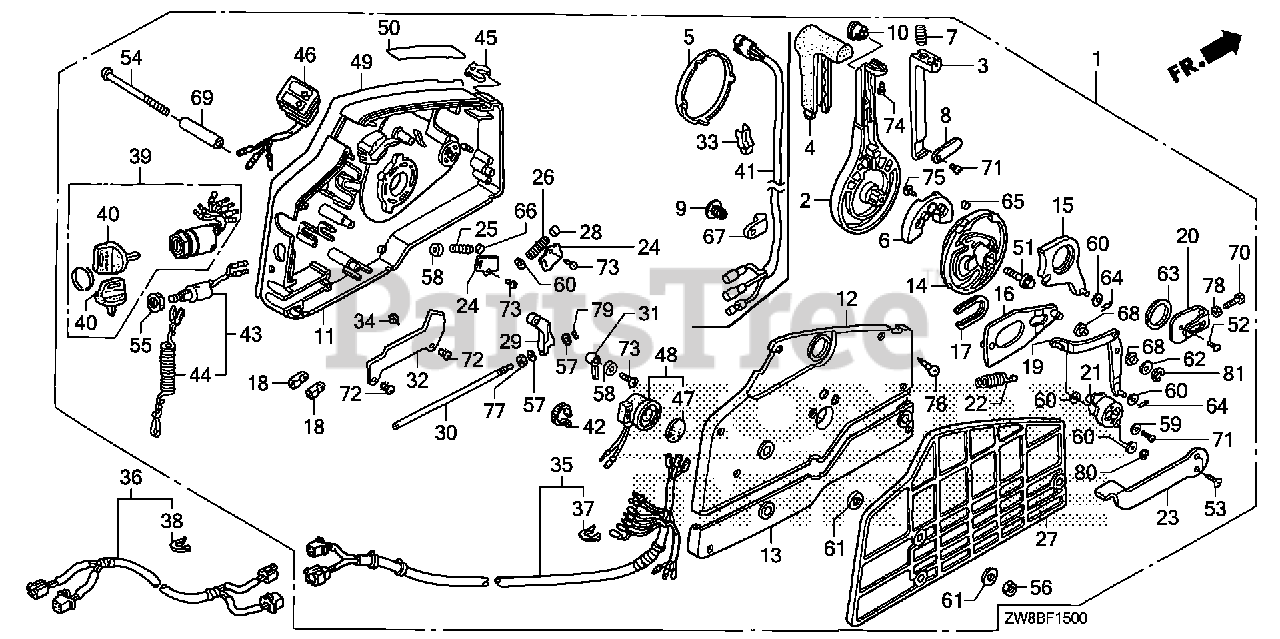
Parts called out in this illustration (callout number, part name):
1	S/R SW 2 LIGH MAN TL
1	BOX ASSY., REMOTE CONTROL (HI-LEX)
2	HANDLE, REMOTE CONTROL
3	LEVER, HANDLE LOCK
4	GRIP, REMOTE CONTROL HANDLE
5	CAP, HANDLE
6	BLOCK, NEUTRAL LOCK
7	SPRING, REMOTE CONTROL HANDLE
8	PLATE, LEVER SETTING
10	COVER, GRIP
11	HOUSING, REMOTE CONTROL BOX (A)
12	HOUSING, REMOTE CONTROL BOX (B)
13	HOUSING, REMOTE CONTROL BOX (C )
14	WHEEL, CONTROL
15	ARM, SHIFT LINK
16	PLATE, SLIDING
17	COLLAR, SLIDING PLATE
18	PIVOT, SHIFT
19	ARM, LINK JOINT
20	BRACKET, LINK JOINT
21	WHEEL, ACCELERATOR
22	SPRING, ACCELERATOR WHEEL
23	LEVER, IDLE
24	PLATE, SPRING SETTING
25	SPRING, SHIFT CLICK
26	SPRING, CHOKE RETURN
27	SPACER, REMOTE CONTROL BOX
28	SPACER, CLICK SPRING
29	BLOCK, THROTTLE FRICTION
30	BOLT, FRICTION
31	SPACER, NEUTRAL SWITCH
34	SPACER, CABLE CLAMP
35	CABLE ASSY. B, REMOTE CONTROL (4P+6P)
36	CABLE ASSY., REMOTE CONTROL EXTENSION (4P+4P)
36	CABLE ASSY., REMOTE CONTROL EXTENSION (4P+6P)
37	TIE, CABLE (NATURAL 2.4X92) Use up to Frame SN 1300359.
38	TIE, CABLE (NATURAL 2.4X92) Use up to Frame SN 1300359.
39	SWITCH ASSY., COMBINATION DUAL QTY = (2) (SINGLE)
40	KEY ASSY., COMBINATION SWITCH (35100-ZV5-003 ONLY) DUAL QTY = (4) (SINGLE)
42	BAND (BLACK 3.5X140)
43	SWITCH ASSY., EMERGENCY STOP
44	WIRE, EMERGENCY (SINGLE) (DUAL)
45	CLIP, EMERGENCY LOCK
46	LAMP ASSY., INDICATOR
47	PLATE, TURN SIGNAL BUZZER DUAL QTY = (2) (SINGLE)
48	BUZZER, WARNING DUAL QTY = (2) (SINGLE)
49	PLATE, REMOTE CONTROL (CAUTION=SILVER)
49	PLATE, REMOTE CONTROL (CAUTION PICT=SILVER) (FOR 4-LED)
49	PLATE, REMOTE CONTROL (COUTION COLOR=RED & YELLOW)
50	MARK, FAST IDLE
51	BOLT, FLANGE (8X35) Use from Frame SN 4800713.
52	SCREW, PAN (6X10)
53	SCREW, FLAT (5X12) Use from Frame SN 4800713.
54	SCREW (6X95)
55	NUT, HEX. (16MM) DUAL QTY = (2) (SINGLE)
56	NUT, HEX. (6MM)
57	WASHER, PLAIN (4MM) Use from Frame SN 4800713.
58	WASHER, PLAIN (5MM)
59	WASHER, PLAIN (5MM)
60	WASHER, PLAIN (6MM) Use from Frame SN 4800713.
61	WASHER (6MM)
62	WASHER, PLAIN (8MM) Use from Frame SN 4800713.
63	WASHER (28MM)
64	PIN, LOCK (6MM)
65	PIN (6X6)
66	ROLLER, CLICK
68	COLLAR, LINK JOINT
69	COLLAR, DISTANCE (6X10X43.5)
70	BOLT, HEX. (5X16)
71	SCREW, PAN (5X10)
73	SCREW, TAPPING (5X10)
74	SCREW, TAPPING (5X12)
75	SCREW, TAPPING (6X16)
76	SCREW, TAPPING (5X25)
77	NUT, HEX. (6MM)
78	NUT, HEX. (5MM)
79	E-RING (3MM)
80	E-RING (4MM)
81	E-RING (7MM)
